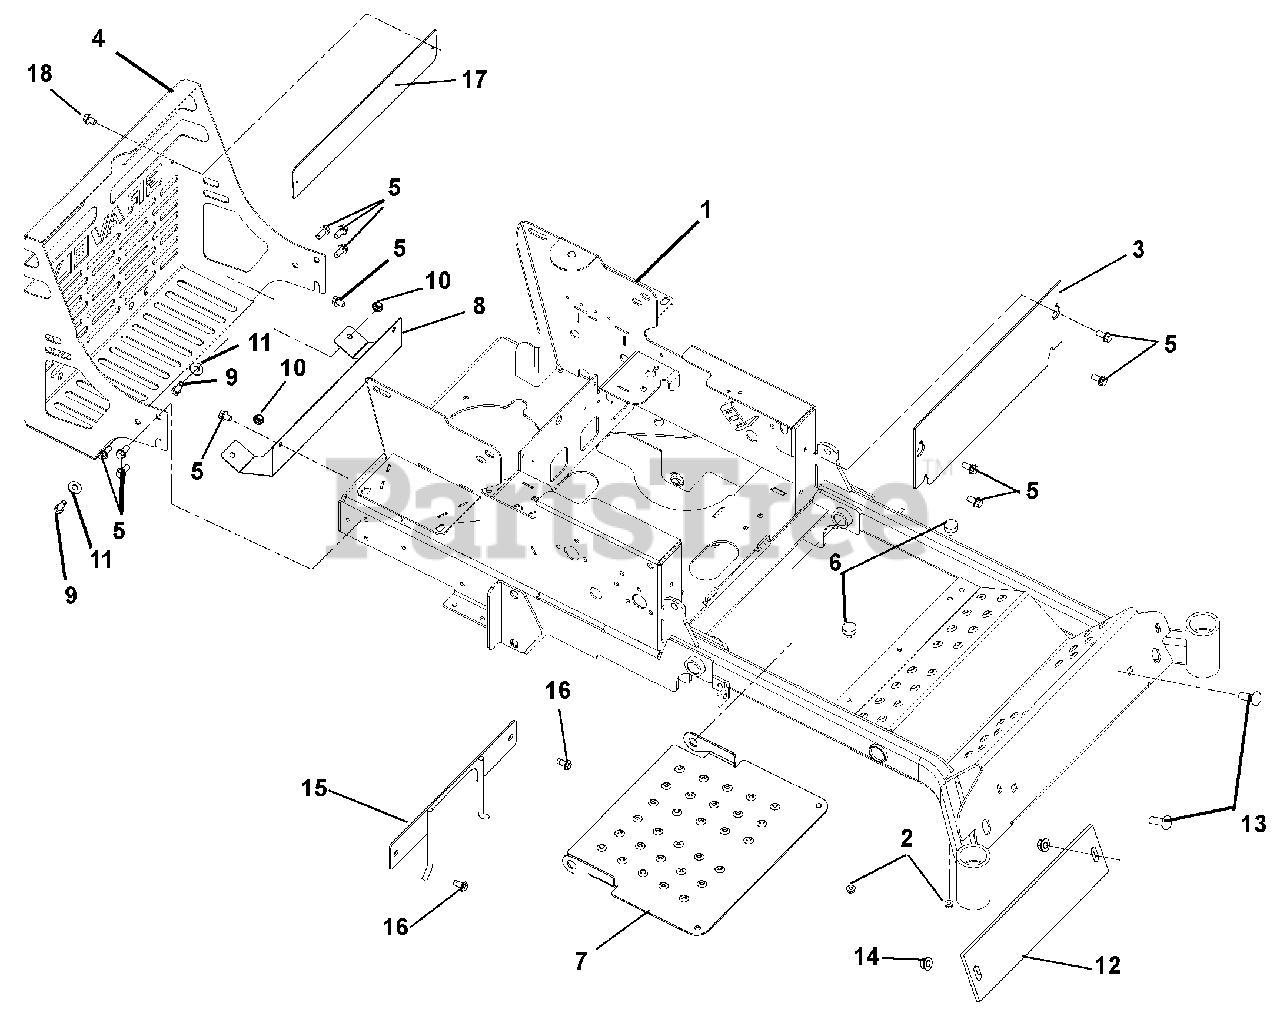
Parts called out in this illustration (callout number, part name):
1	WLDMT, 48" HD FRAME
2	@NUT-SPNLK-FLG .312-18 YWZC
3	KICK PLATE - RED
4	BUMPER, GRAVELY HD
5	@SCR-TAP .38-16X.75 HWH TR YWZ
6	BUMPER, RUBBER
7	PANEL, INSPECTION
8	SHIELD - HEAT - CZ PROD
9	@BLT-HEX .38-16X1.00 GR5 YWZC
10	@NUT-LK-NYL-FLG .38-16 YWZC
11	@WSHR-FL-STL.438X1.00X.083 YWZ
12	COUNTERWEIGHT CZ FRONT - RED
13	BLT-RDHDSQNK .50-13X2.25 G5YZ
14	@NUT-LK-NYL-FLG .50-13 YWZC
15	PTO BELT FINGER WLDMT - BLK
16	@SCR-TAP .38-16X.75 HWH TR YWZ
17	BUMPER BACKER PLATE - BLACK
18	@SCR-TAP .25-20X.50 HWH TR YWZ
